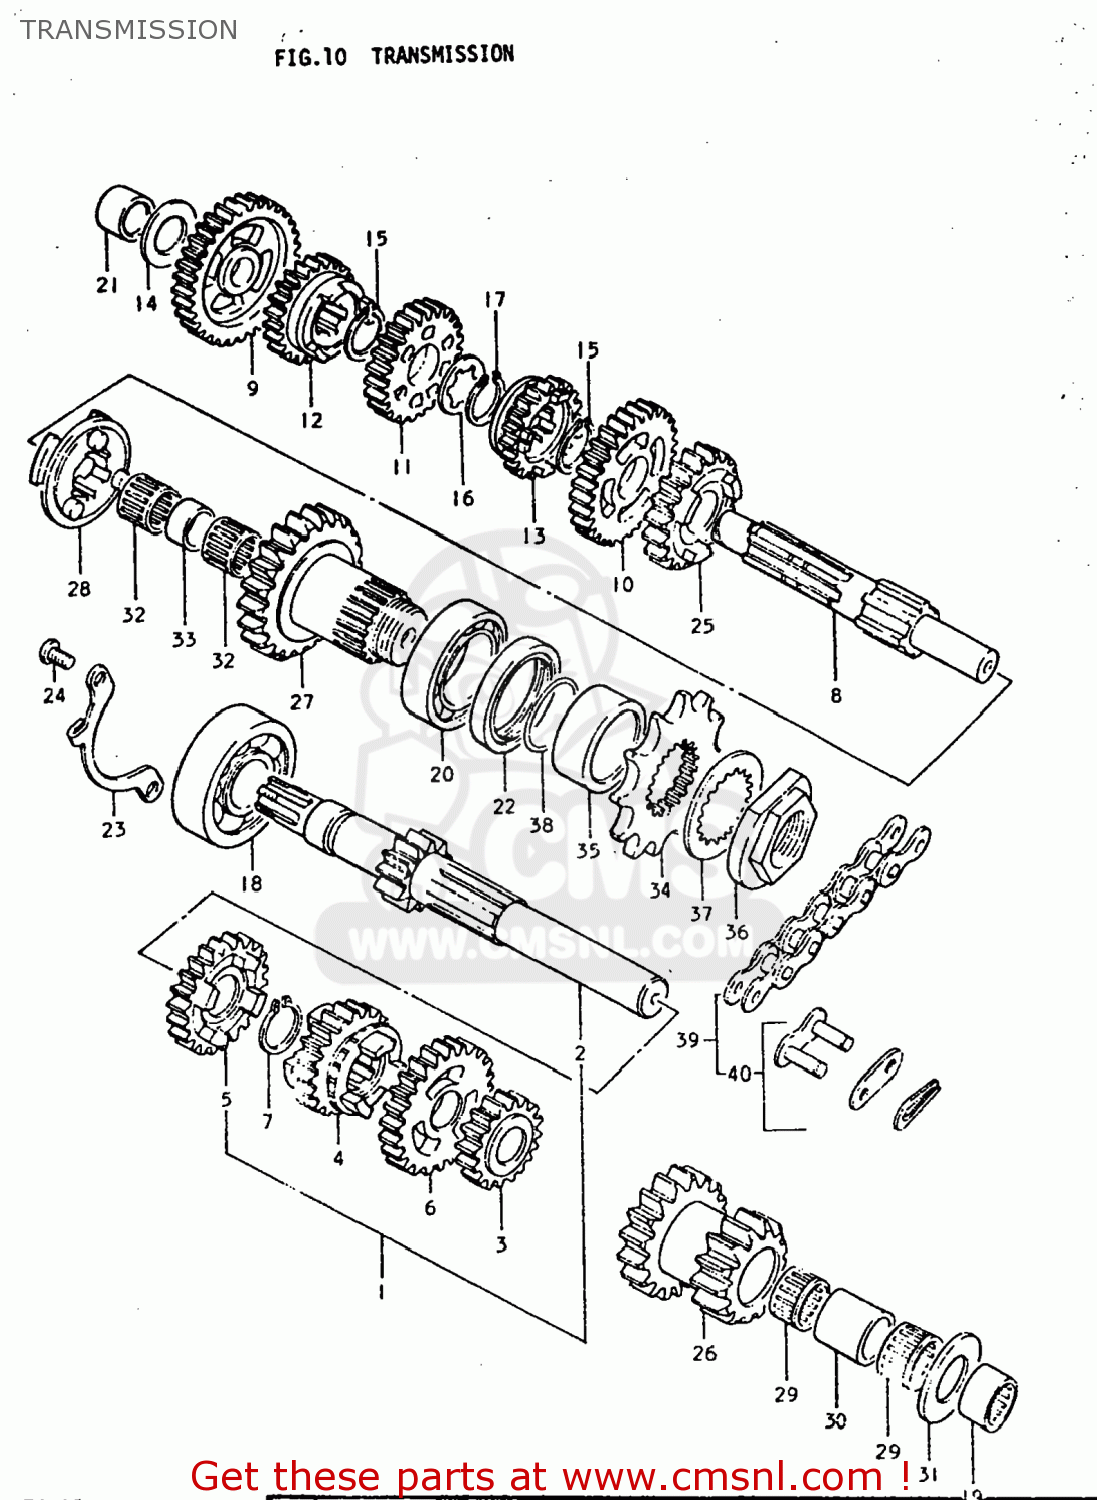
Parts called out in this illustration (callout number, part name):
1	SHAFT,COUNTER
2	SHAFT,COUNTER
3	GEAR,SECOND DRIVE
4	GEAR,THIRD DRIVE
5	GEAR,FOURTH DRIVE
6	GEAR,FIFTH DRIVE
7	CIRCLIP
8	SHAFT,DRIVE
9	GEAR,1ST DRIVEN
10	GEAR,SECOND DRIVEN
11	GEAR,THIRD DRIVEN
12	GEAR,FOURTH DRIVEN
13	GEAR,FIFTH DRIVEN
14	WASHER
15	CIRCLIP
16	WASHER
17	CIRCLIP
18	BEARING
19	ROLLER BEARING (17X24X1
20	BEARING
21	BUSH
22	OIL SEAL (38X50X8)
23	RETAINER,CNTR SHAFT BEARING
24	SCREW
29	BEARING(17X21X12.8)
30	SPACER
31	WASHER
32	ROLLER BEARING (15X19X1
33	SPACER
34	SPROCKET,ENGINE
35	SPACER
36	NUT
37	WASHER
38	O-RING
39	CHAIN ASSEMBLY,DRIVE
40	JOINT ASSEMBLY,CHAIN
